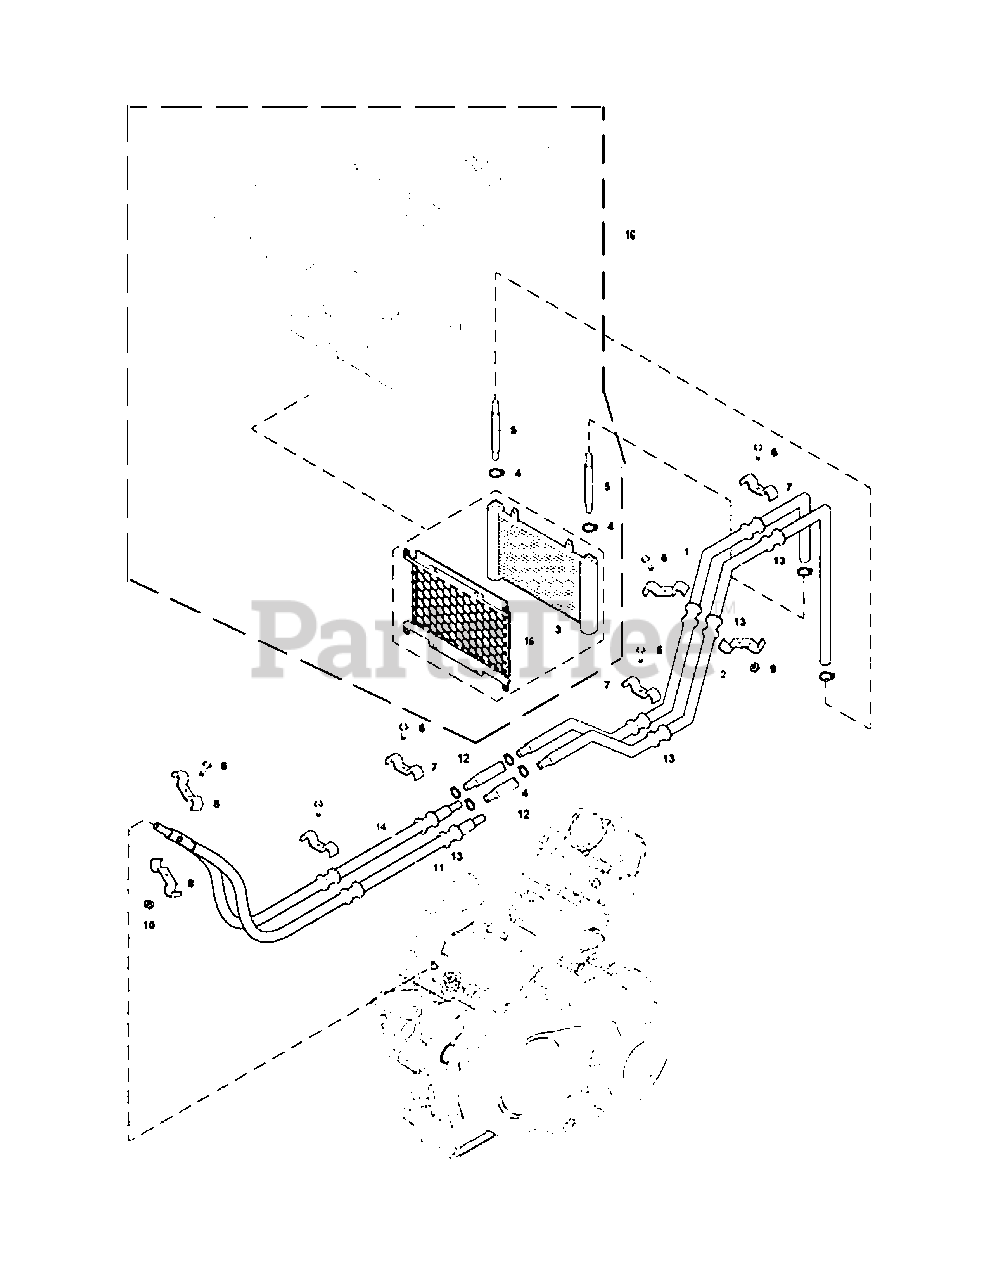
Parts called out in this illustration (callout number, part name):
1	Oil Cooler Cover
2	Front Right Metal Oil Pipe
3	Oil Cooler Assy
4	Screw Hoop12-20
5	Rubber Oil Pipe A
6	Hexagon Flange Bolt M6×12
7	M-Shaped Fixed Pipe Clamps
8	M-Shaped Fixed Pipe Clamps
9	Hexagon Flange Nut M6
10	Hexagon Bolt M6
11	Rear right Metal Oil Pipe
12	Rubber Oil Pipe B
13	I-Shaped Rubber Washer
14	Rear left Metal Oil Pipe
15	Front Left Metal Oil Pipe
16	Oil Cooler Cover
16	Radiator comp
